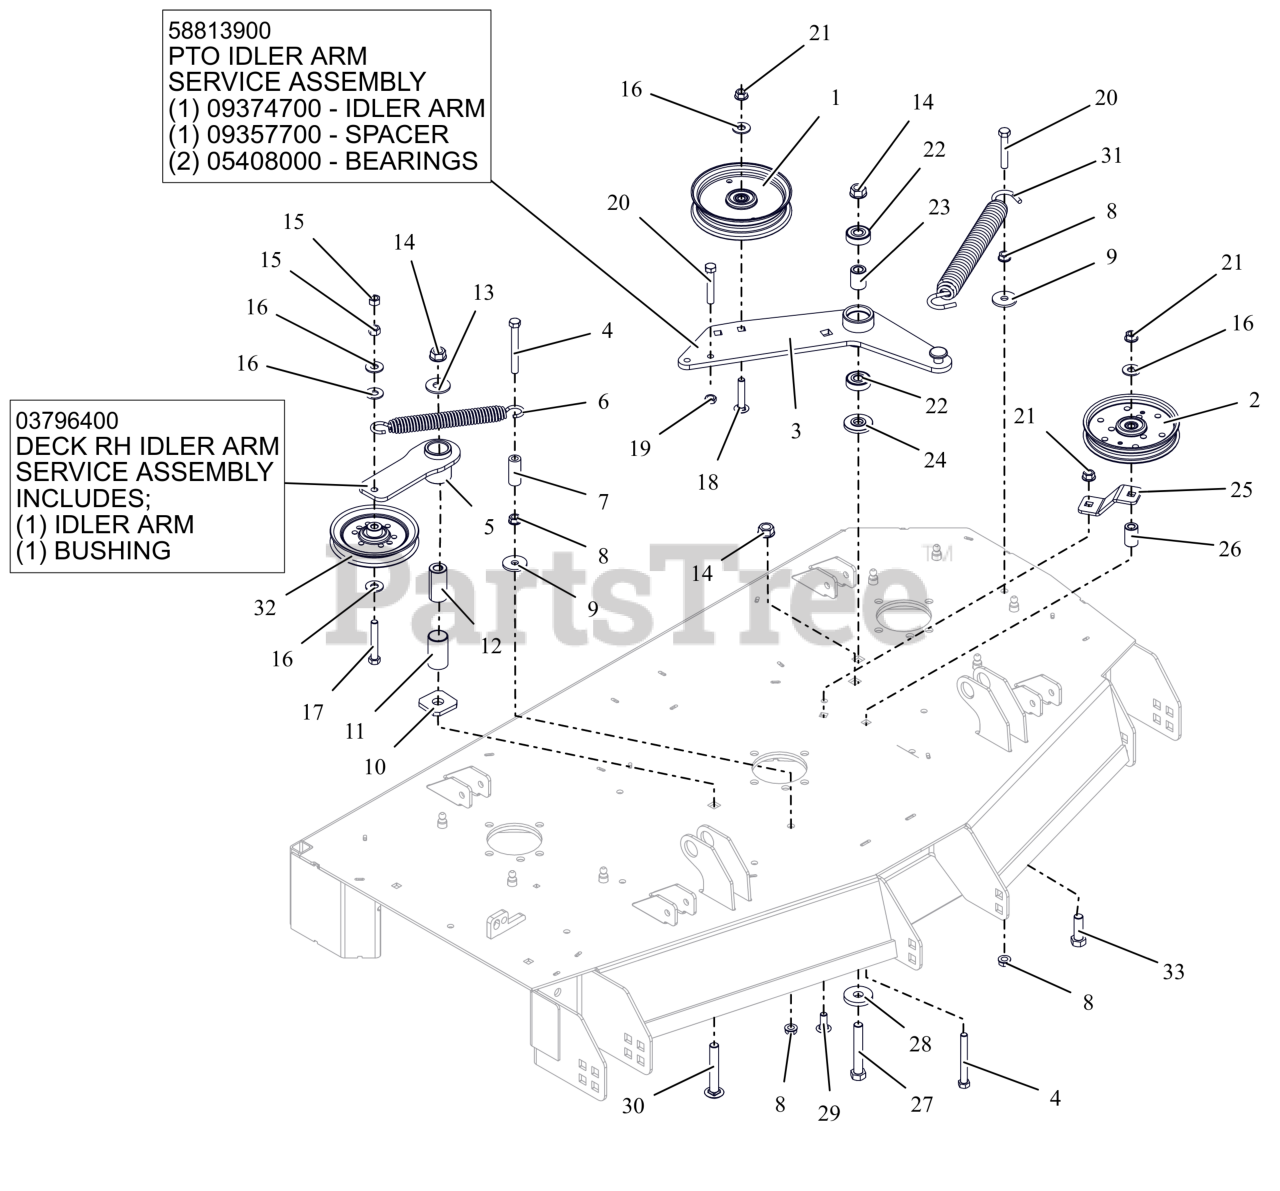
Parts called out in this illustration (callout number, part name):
1	IDLER- FLAT - 5.00" X .75"
2	IDLER- 5" FLANGED
3	WLDMT, IDLER ARM PT660
3	PTO IDLER ARM
3	SPACER .510 X .867 X 1.1485
3	BRG-BALL .500X1.38X.437
4	BLT, HEX .38-16X3.25 G5 ZCC
5	WMT, IDLER ARM - BLACK
5	ASM, IDLER ARM (DECK)
6	SPRING- EXTENSION
7	HOSE, .38 X 1.65
8	NUT, SPNLK-FLG .38-16 G5 ZCC
9	WSHR,FLT .406X1.375X.135 ZCC
10	WSHR-FLT .640X1.75X.250
11	BSHG, 1.00X1.125X1.937
12	BSHG, SPCR .502X.997X2.03 PM
13	WSHR,FLT .563X1.375X.109 ZCC
14	NUT-LK-CTR-FLG .500-13 GG ZCC
15	NUT-LK-CTR .38-16 ZC120
16	WSHR,FLT .438X1.00X.083 ZCC
17	BLT, HEX .38-16X2.50 G5 ZCC
18	BLT,RHSSN.375-16X2.00 G5 ZCC
19	NUT-JAM .375-16 G2 ZCC
20	BLT,HEX .38-16X2.25 G5 ZCC
21	NUT-LK-CTR-FLG .375-16 GF ZCC
22	BRG-BALL .500X1.38X.437
23	SPACER .510 X .867 X 1.1485
24	SPACER, IDLER ARM
25	PTO FIXED IDLER MTG BRKT -RED
26	BUSHING, SLV .380X.750X1.190
27	BLT,HEX .50-13X3.25 G5 ZCC
28	WSHR-FL-STL 0.557X1.625X0.25 ZCC
29	BLT,RHSSN .38-16X1.00 G5 ZCC
30	BTL,RHSSN .500-13 X 3.25 G5 ZCC
31	SPRING, EXTENSION
32	IDLER, V, 5.00X.38
33	BLT,HEX .50-13X1.50 G5 ZCC
